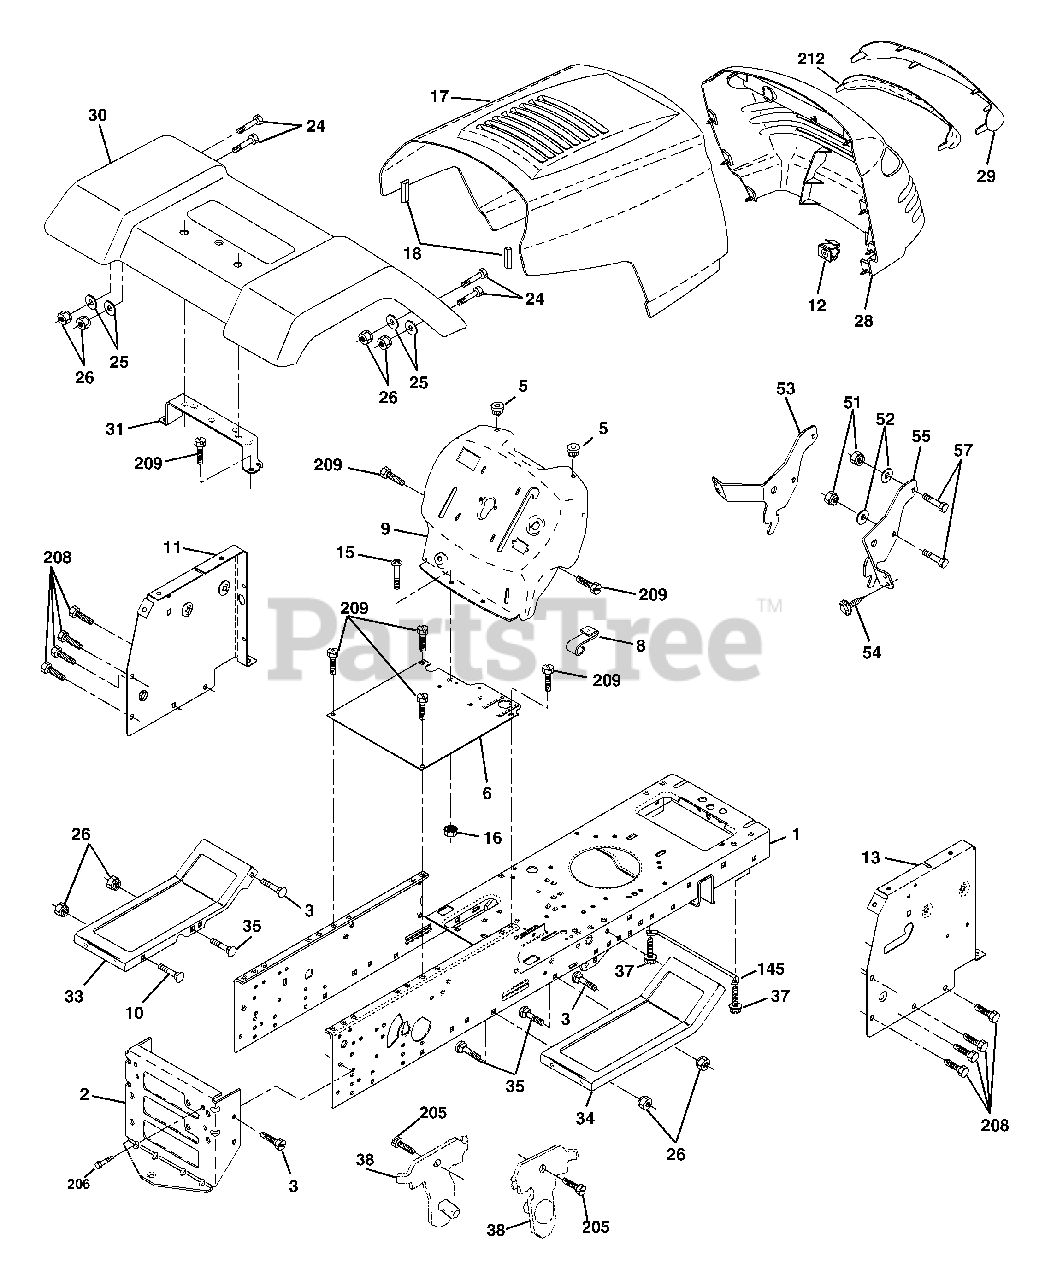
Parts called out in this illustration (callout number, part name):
1	Chassis
2	Drawbar, Stretch
3	Screw 3/8-16 x 3/4
5	Bumper, Hood/Dash
6	Saddle Silkscreen Flt Sdl
8	Clip Retainer Slide-On
9	Dash
10	Bolt, Carriage 3/8-16 x 1
11	Panel Dash LH
12	Clip Tinnerman Grille P.L
13	Panel Slkscr Dash RH
15	Screw Mach TRHD 5/16-18uncx3/4
16	Nut Keps 5/16-18 Unc
17	Hood
18	Bumper Hood
24	Bolt Fin Hex 3/8-16unc X 1 Gr. 5
25	Washer 13/32 X 13/16 X 12 Ga
26	Nut Lock Hex w/Ins 3/8-16 Unc
28	Grille/Lens Asm
29	Lens Grille Private Label
30	Fender
31	Bracket Fender Repl 109873x
33	Footrest Pnt LH
34	Footrest Pnt RH
35	Bolt Rdhd Sht Sqnk 3/8-16 X3/4
37	Screw Thdrol 5/16-18 x 1/2 TYT
38	Bracket Asm. Pivot Mower Rear
51	Nut Lock W/Insert 1/4-20unc
52	Washer 9/32 x 7/8x16 Ga.
53	Bracket Grille Lh
54	Screw Hex 8-18 x 7/8
55	Bracket Grille Rh
57	Bolt Fin Hex 1/4-20 unc x .75
145	Rod Pivot Chassis/Hood
205	Screw Thdrol 3/8-16 x 1/2
206	Bolt Shoulder 5/16-18
208	Screw Thdrol 3/8-16 x 1/2
209	Screw Hex Wsh Thdrol 3/8-16
212	Insert Lens Reflect
